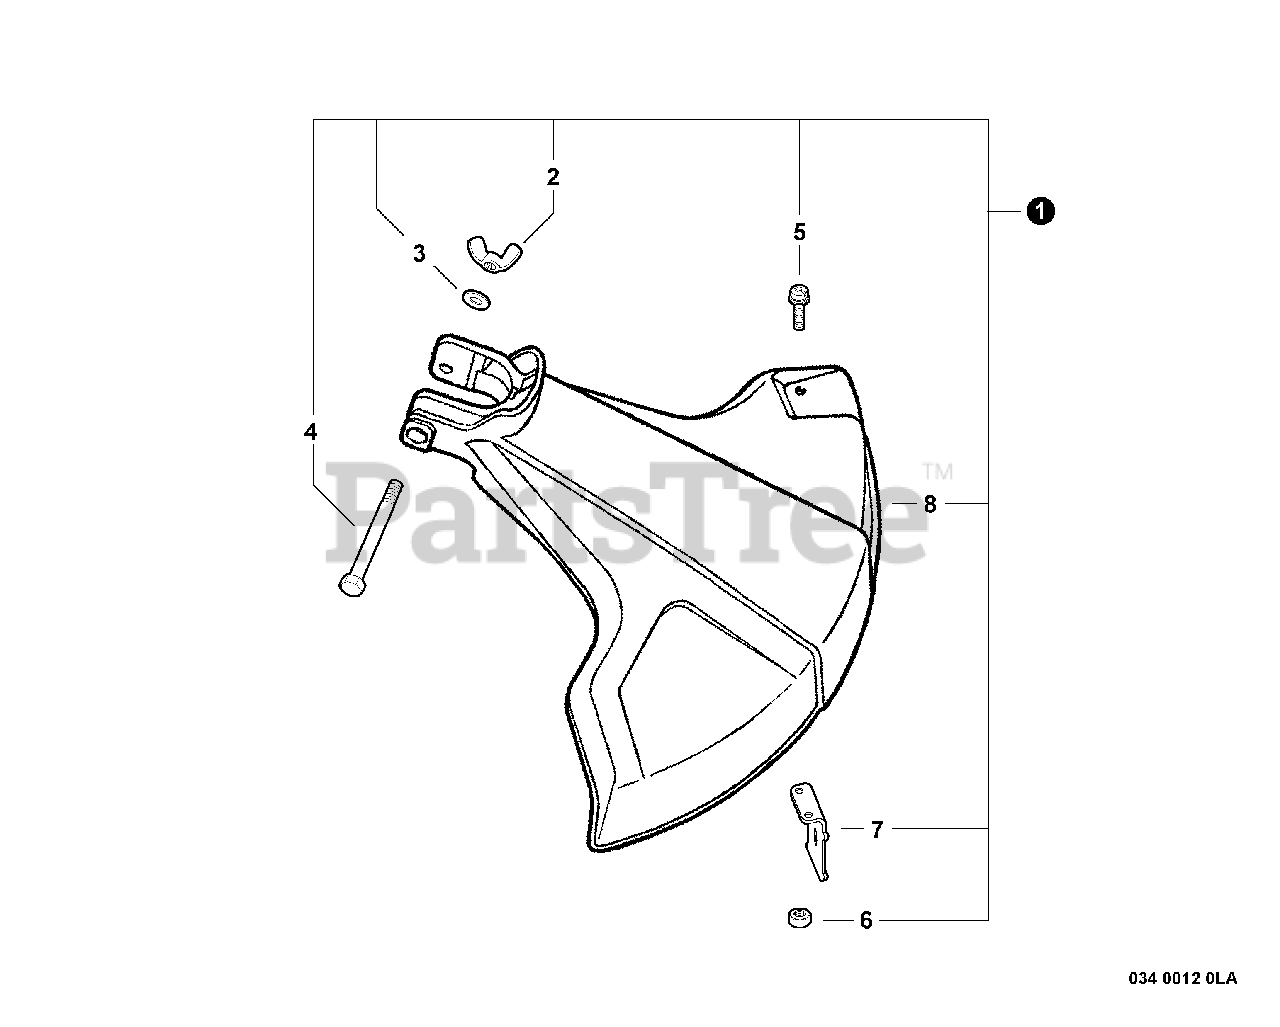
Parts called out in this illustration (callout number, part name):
1	DEBRIS SHIELD KIT
2	NUT, WING 1/4"-20
3	WASHER 6
4	BOLT 1/4"-20×2"
5	SCREW 5×12
6	NUT M5
7	CUTTER, LINE
8	SHIELD, DEBRIS
